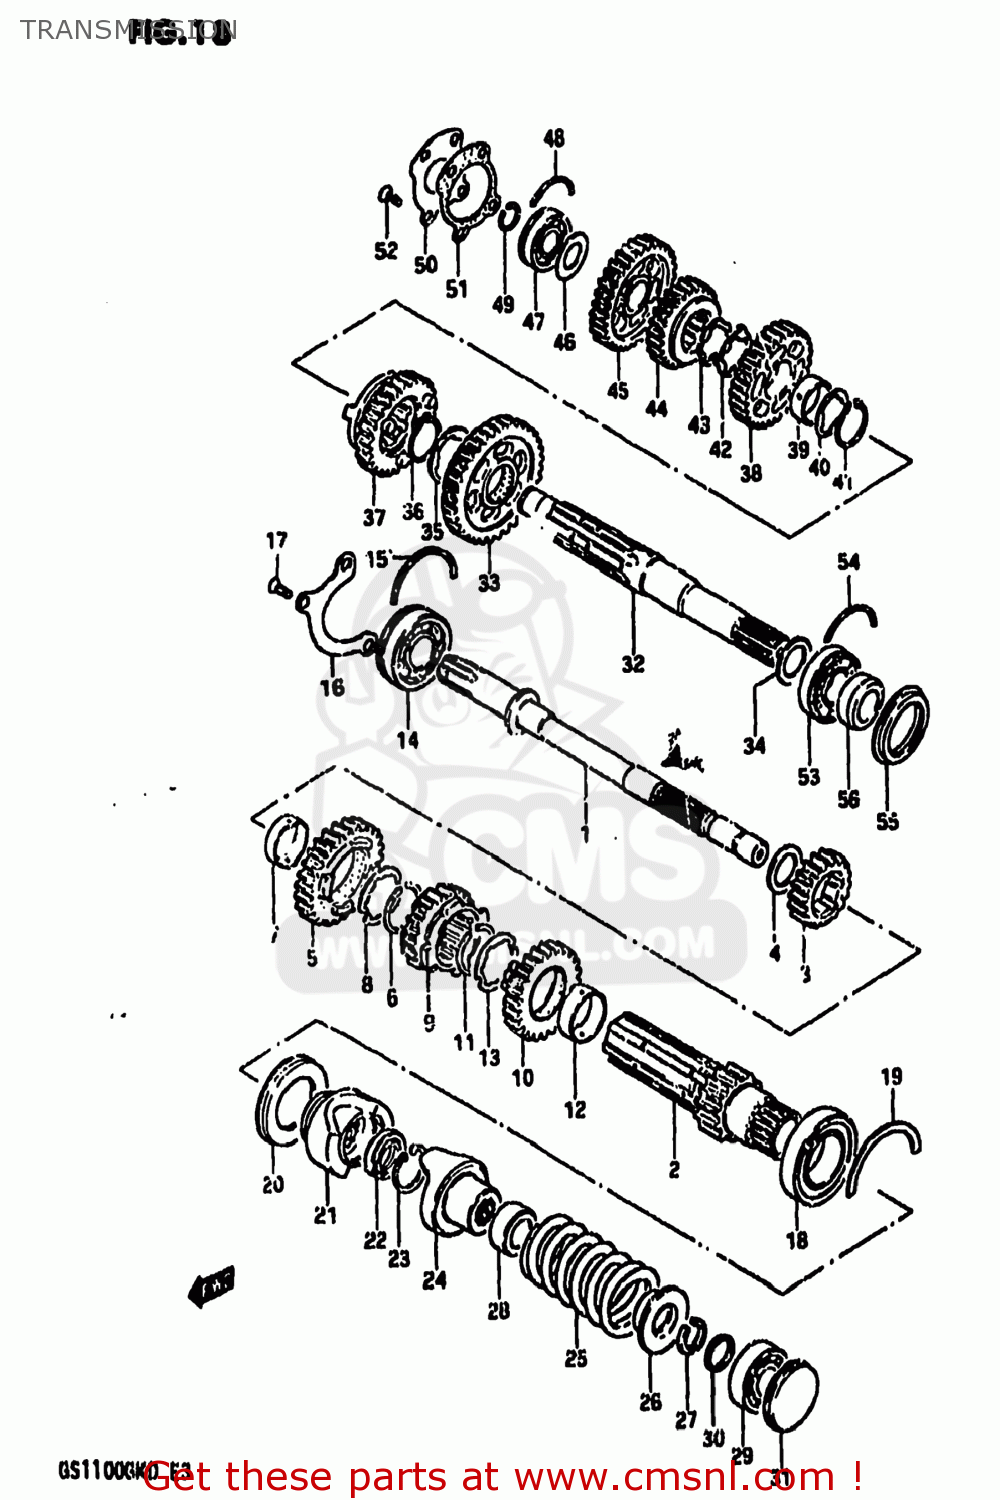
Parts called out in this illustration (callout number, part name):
1	SHAFT,COUNTER
2	SHAFT,OUTER COUNTER
3	GEAR,SECOND DRIVE
4	WASHER (21X35X2)
5	GEAR,5TH DRIVE(NT:26)
6	RING,SNAP
7	SPACER,DRIVE GEAR
8	LOCK WASHER,5TH DR GEAR SPACER
9	GEAR,THIRD DRIVE
10	GEAR,FOURTH DRIVE
11	RING,SNAP
12	SPACER,DRIVE GEAR
13	LOCK WASHER,5TH DR GEAR SPACER
14	BEARING(25X62X17)
15	C-RING
16	RETAINER,CNTR SHAFT BEARING
17	SCREW
18	BALL BEARING 32X58X13
19	C-RING
20	SEAL,OIL(40X58X7)
21	DOG,OUTPUT CAM
22	SEAL,OIL(20.6X31X6)
23	CIRCLIP
24	DOG,INPUT CAM
25	SPRING
26	STOPPER,CAM DOG SLIDING
27	STOPPER,CAM DOG
28	GUIDE,CAM DOG SPRING
29	BEARING
30	SPACER (17X21X3.5)
31	PLUG
32	SHAFT,DRIVE
33	GEAR,FIRST DRIVEN
34	WASHER, LH
35	WASHER,LOCK
36	CIRCLIP
37	GEAR,FOURTH DRIVEN
38	GEAR,THIRD DRIVEN
39	BUSH,3RD DRIVEN GEAR
40	WASHER,LOCK
41	CIRCLIP
42	WASHER
43	WASHER,LOCK
44	GEAR,FIFTH DRIVEN
45	GEAR,SECOND DRIVEN
46	WASHER
47	BEARING(20X47X14)
48	C RING
49	CIRCLIP
50	PLATE,DRIVESHAFT
51	GASKET,DRIVESHAFT PLATE (MCA)
52	SCREW
53	BEARING
54	C RING
55	SEAL,OIL(35X52X6)
56	SPACER,DRIVESHAFT,LEFT
